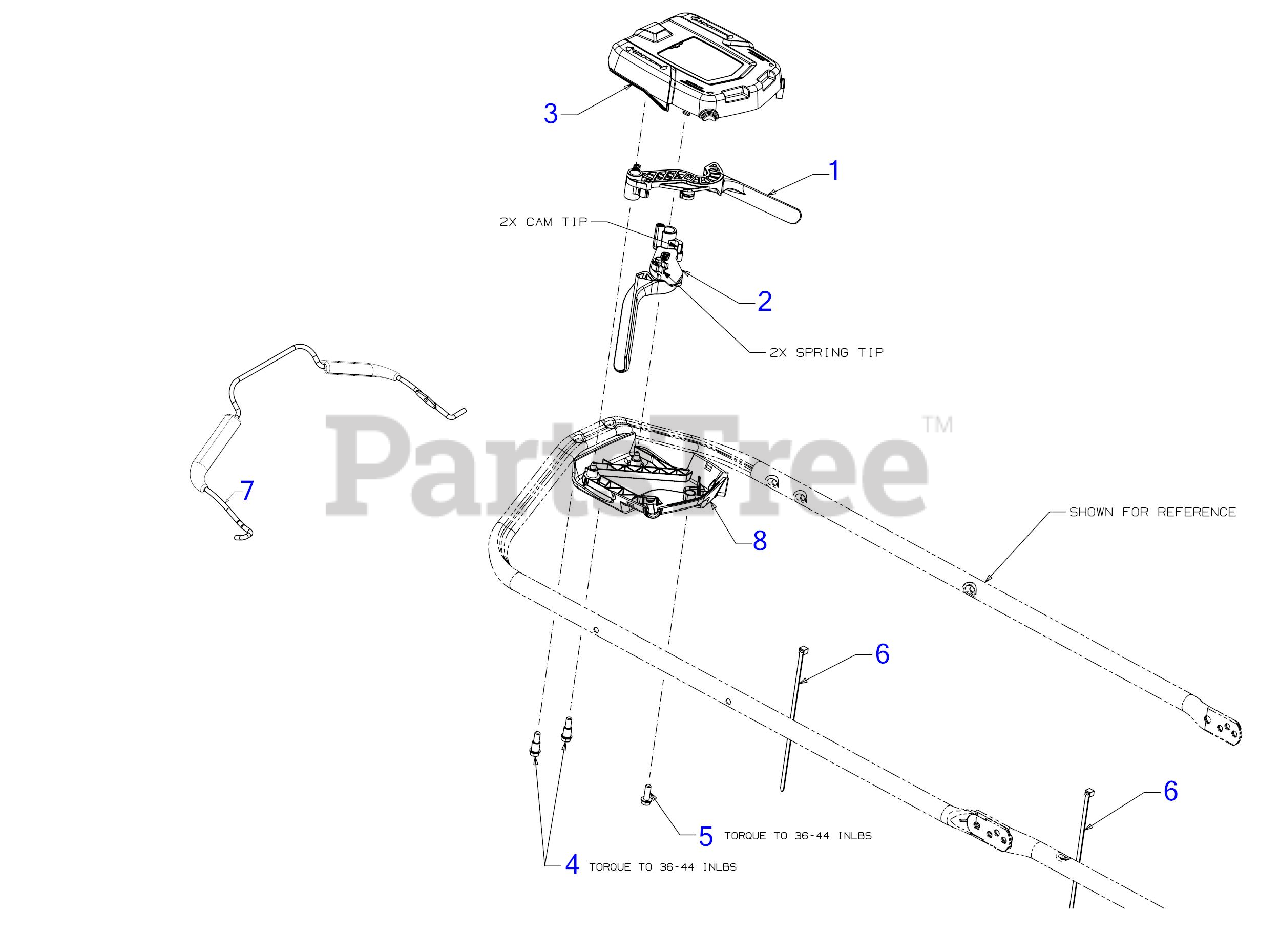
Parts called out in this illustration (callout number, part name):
1	AWD CONTROL LEVER (LH) (BLACK)
2	AWD CONTROL LEVER (RH) (BLACK)
3	UPPER CONTROL HOUSING
4	SHOULDER SCREW 1/4-15 x .970
5	SCREW 1/4-15 x .750
6	7" CABLE TIE
7	AWD BAIL ASSEMBLY (YELLOW)
8	LOWER CONTROL HOUSING
